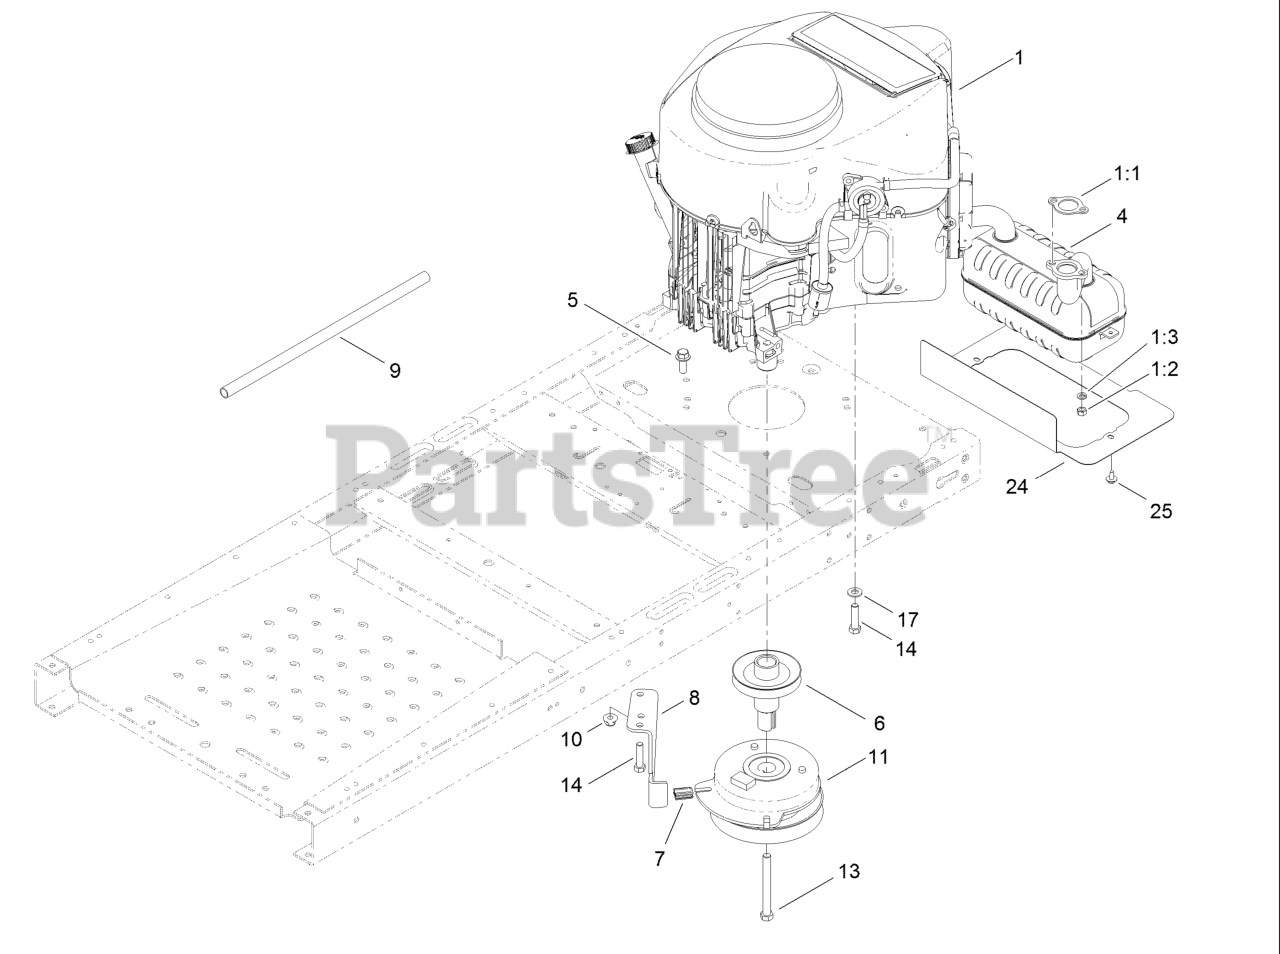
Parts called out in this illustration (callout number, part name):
1:1	GASKET-EXHAUST
1:3	WASHER-LOCK
4	MUFFLER-KAWASAKI
5	SCREW-HHF 3/8-16 X 1
6	PULLEY-ENGINE
7	ISOLATOR-CLUTCH
8	STOP-CLUTCH
9	TUBE-DRAIN, OIL
10	NUT-HF, NI
11	CLUTCH-ELECTRIC, PTO
13	SCREW-HH
14	BOLT-HH
17	WASHER-FLAT
25	SCREW-HHFTF
